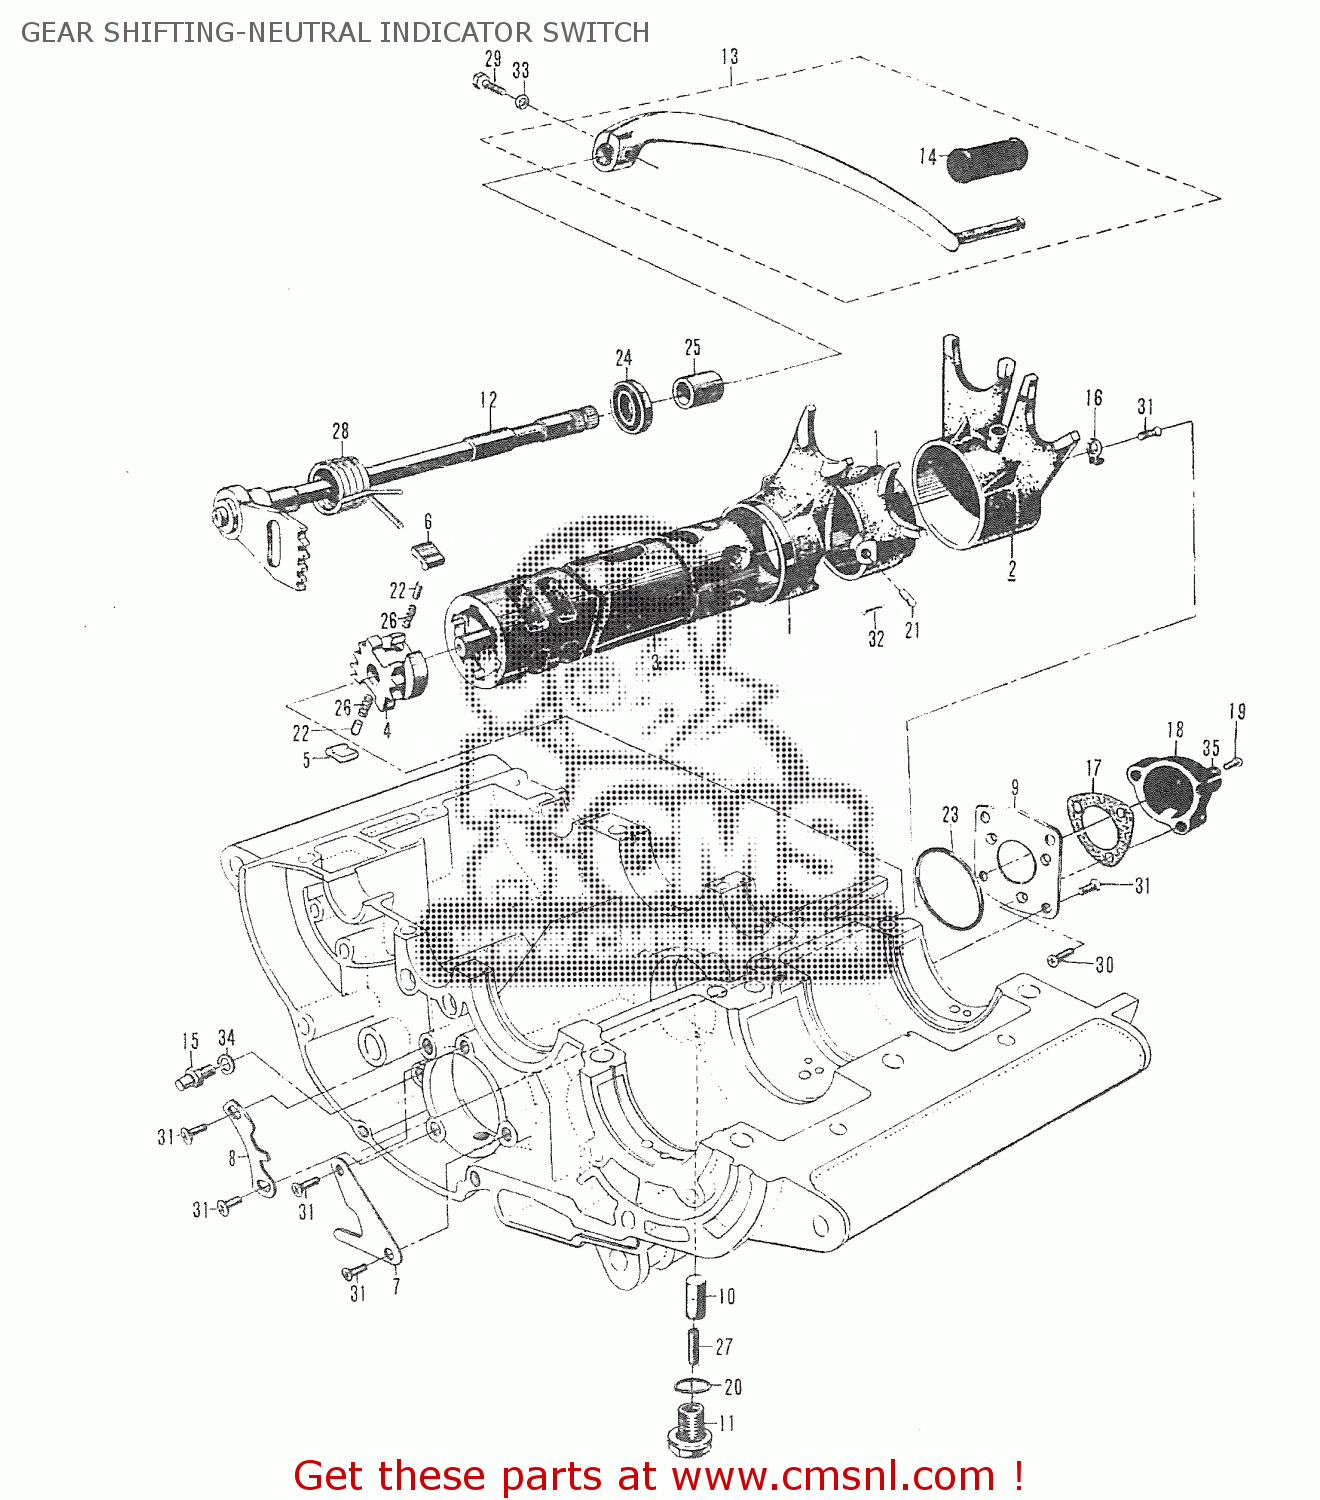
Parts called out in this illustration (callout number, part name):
1	LOW SPEED GEAR SHIFTING FORK
2	HIGH SPEED GEAR SHIFTING FORK
3	GEAR SHIFTING CAM COMP
4	RETAINER,GEAR SHIFT CAM
5	PAWL,GEAR SHIFT NO.1
6	PAWL,GEAR SHIFT NO.2
7	GEAR SHIFTING CAM SIDE PLATE
8	GUIDE,GEAR SHIFTING CABLE
9	GEAR SHIFTING CAM RETAINER
10	STOPPER,GEAR SHIFTING
11	BOLT,GEAR SHAFT CAM STOPPER
12	GEAR SHIFTING SHAFT COMP.
13	GEAR SHIFTING LEVER ASS'Y
14	RUBBER,GEAR SHIFT PEDAL
15	STOPPER,GEAR SHIFT CAM
16	NEUTRAL INDICATOR SWITCH CONTACT
17	NEUTRAL INDICATOR SWITCH GASKET
18	NEUTRAL INDICATOR SWITCH
19	SCREW
20	GASKET(14X19.2X2) (NAS)
21	PIN
22	KICK STARTER SHAFT PAWL ROLLER
23	O RING(D:2.6,ID:47.4)
24	OIL SEAL
25	CUSHION
26	SPRING
27	SPRING
28	SPRING
29	STRONG HEXAGON BOLT
30	CROSS HEAD SCREW
31	CROSS HEAD SCREW
32	COTTER PIN
33	LOCK WASHER
34	LOCK WASHER
35	FLAT WASHER
